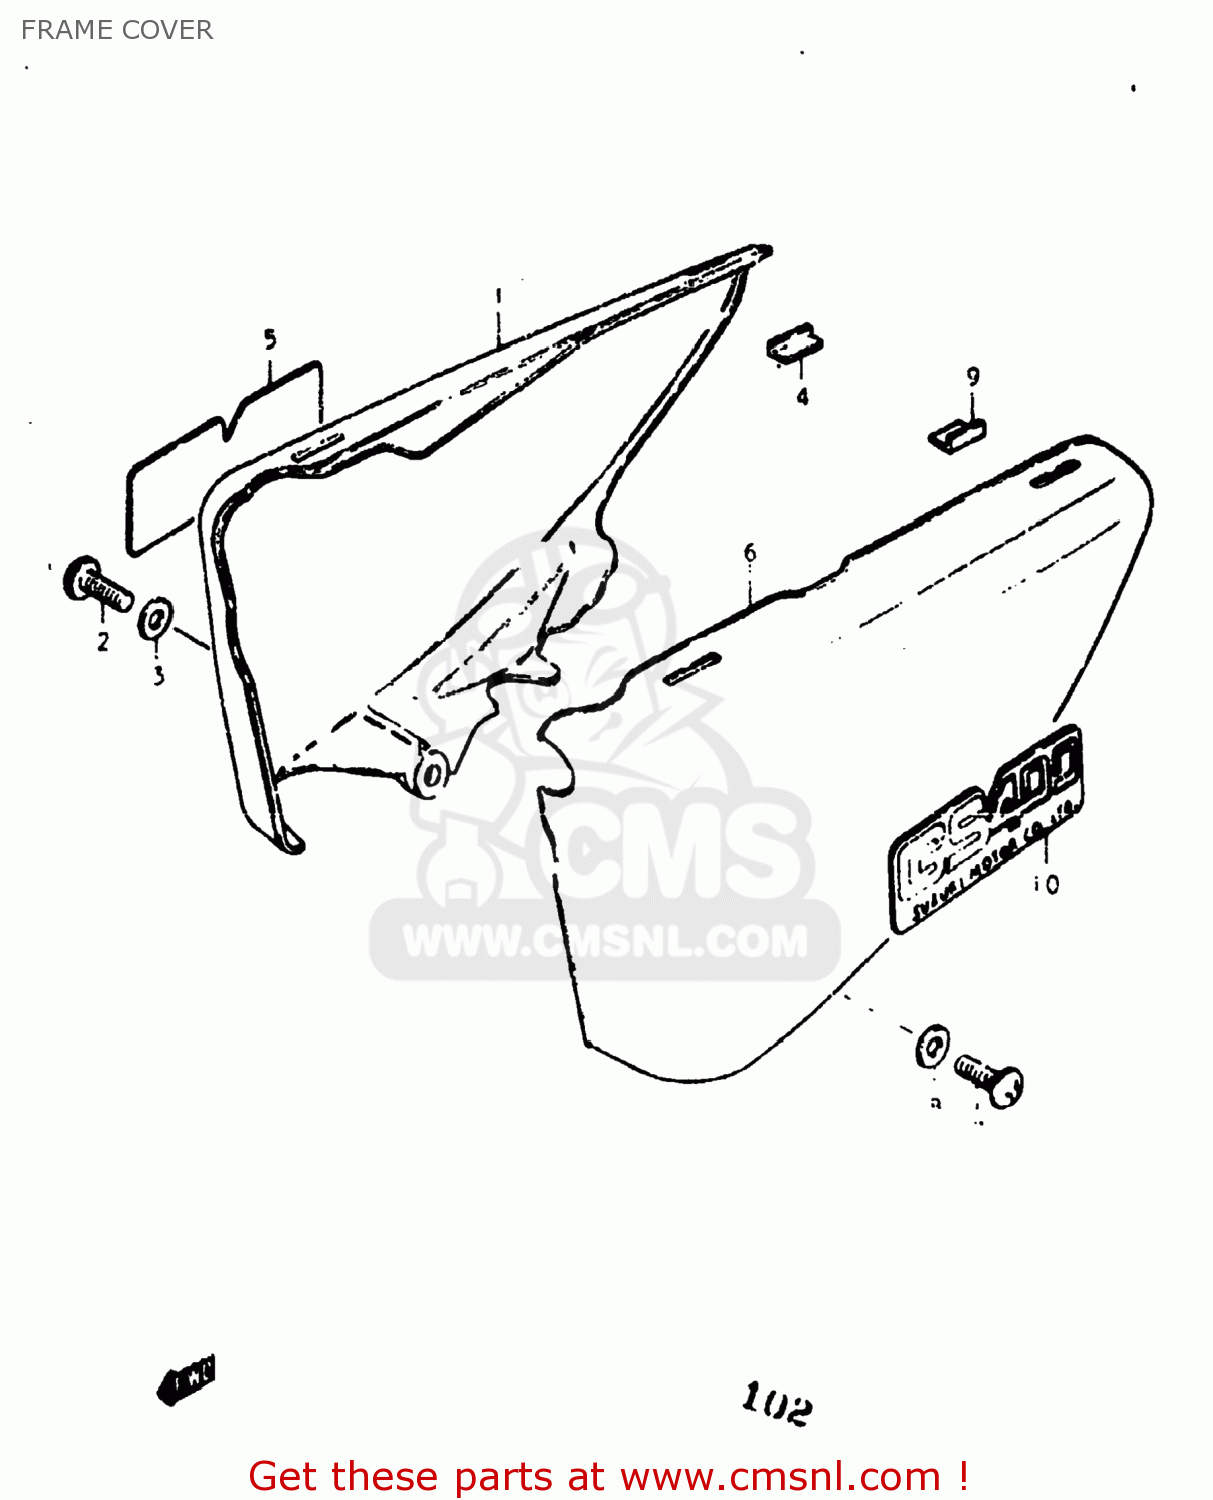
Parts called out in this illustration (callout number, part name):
1	COVER,FRAME,RIGHT
2	SCREW (6X15)
3	WASHER (6.5X18X1.6)
4	CUSHION,FRAME COVER
5	EMBLEM
6	COVER,FRAME,LEFT
7	SCREW
8	WASHER (6.5X18X1.6)
9	CUSHION,FRAME COVER
10	EMBLEM
